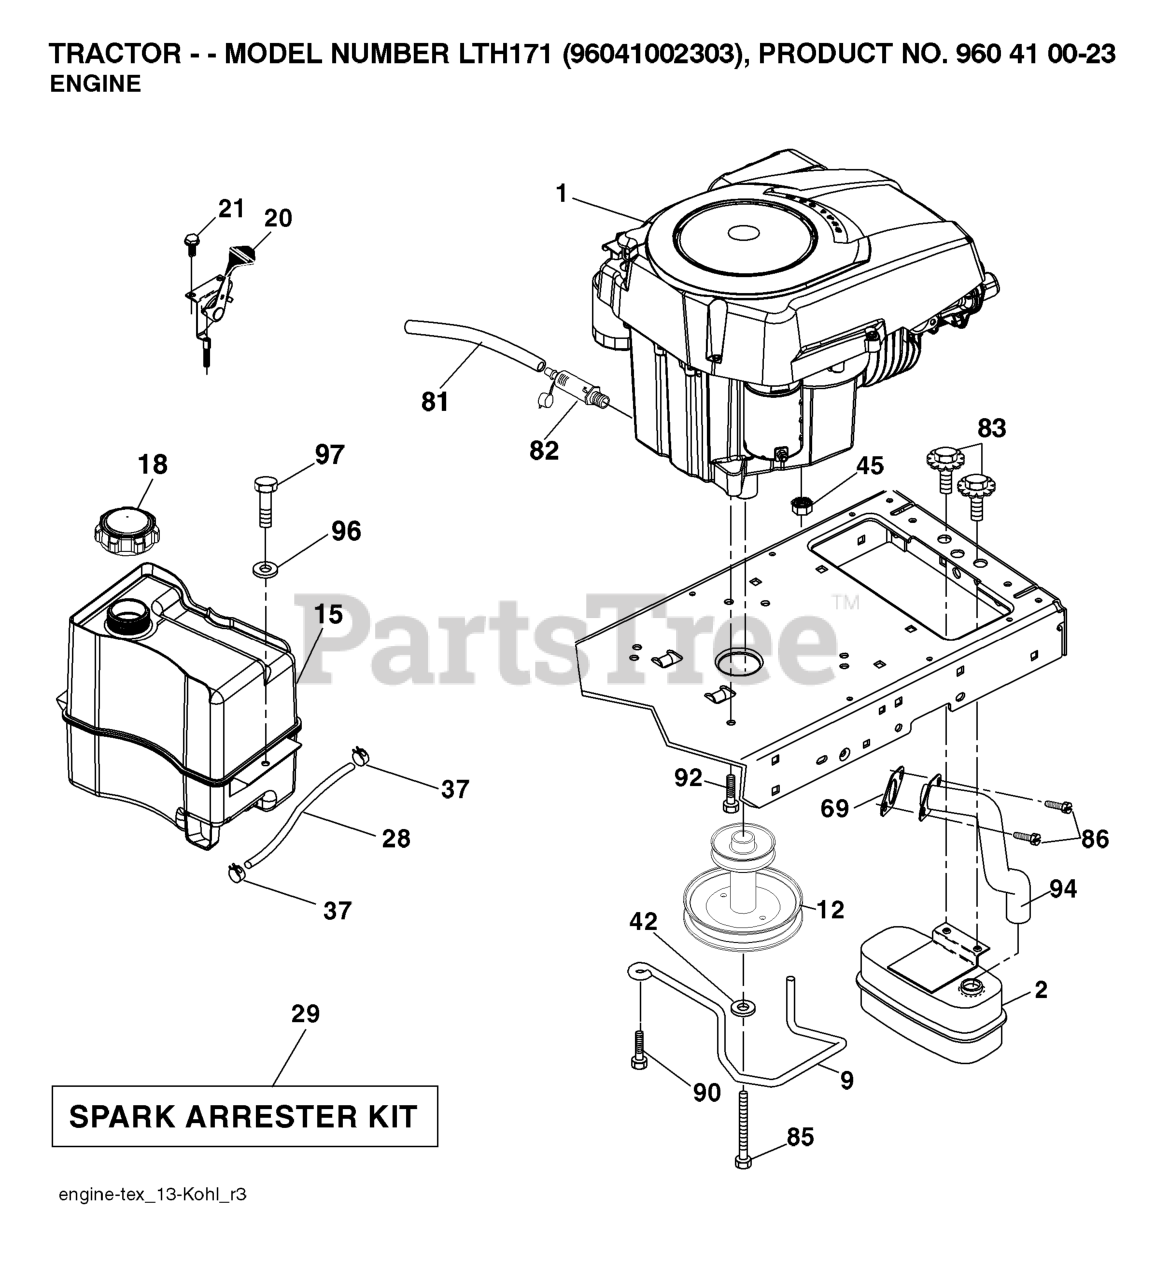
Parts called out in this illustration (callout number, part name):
2	MUFFLER.SINGLE.CYL.KOHL/B&S
9	KEEPER.BELT.ENGINE.4.2
12	PULLY ENGINE
15	RP TANK FUEL FRT 1.5 GAL
18	FUEL CAP
20	CONTROL.TH/CK.C.
21	SCREW.#10 X 0.750.BOS
28	LINE.FUEL.20
29	KIT.SPARK ARRESTOR 794945 B&S
37	HOSE CLAMP
42	LOCKWASHER
45	NUT
69	GASKET.EXHAUST.KOHLER
81	TUBE, DRAIN OIL ASM.
82	PLUG DRAIN OIL EASY
83	BOLT.5/16-18UNCX3/4 W/SEMS.BLK
85	BOLT HEX 7/16-20X4-1/4"
86	SCREW.SOCKET HD.5/16-1
90	SCREW 3/8-16X1
92	SCREW 3/8-16X1
94	RP.TUBE.EXHAUST.KOHL.COURAGE
97	SCREW HEXWSHR 1/4-20X3/4
